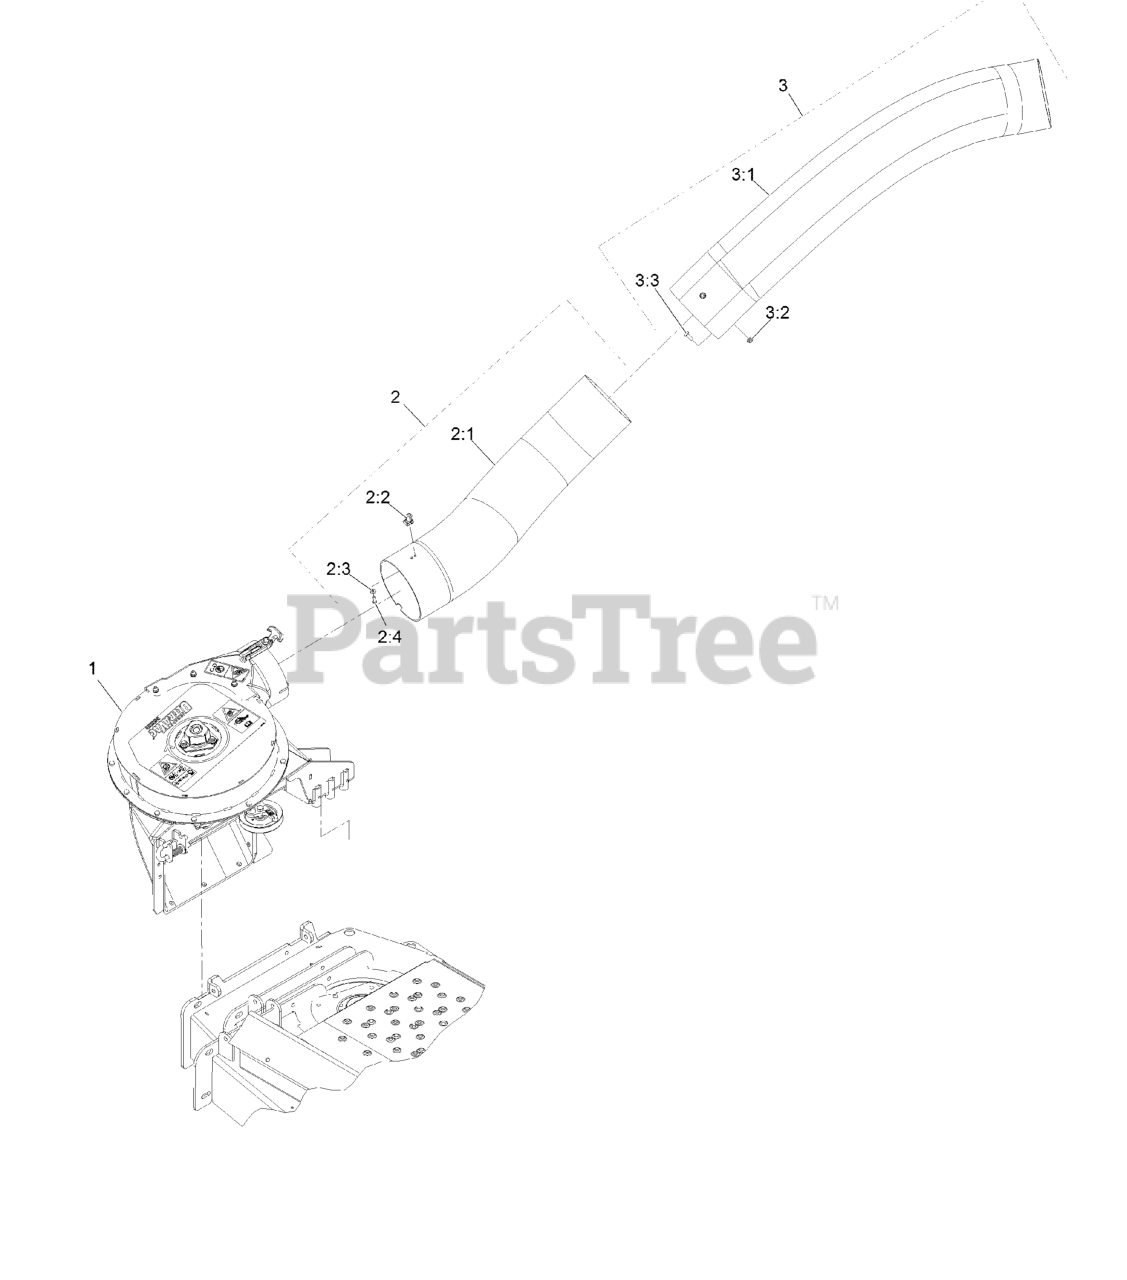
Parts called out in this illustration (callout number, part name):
1	ASM-BLOWER UV E SERVICE
2	LOWER TUBE ASM
2:1	TUBE-LOWER
2:2	LATCH-KEEPER
2:3	WASHER-FLAT
2:4	SCREW-PPH
3	UPPER TUBE ASM
3:1	TUBE-UPPER
